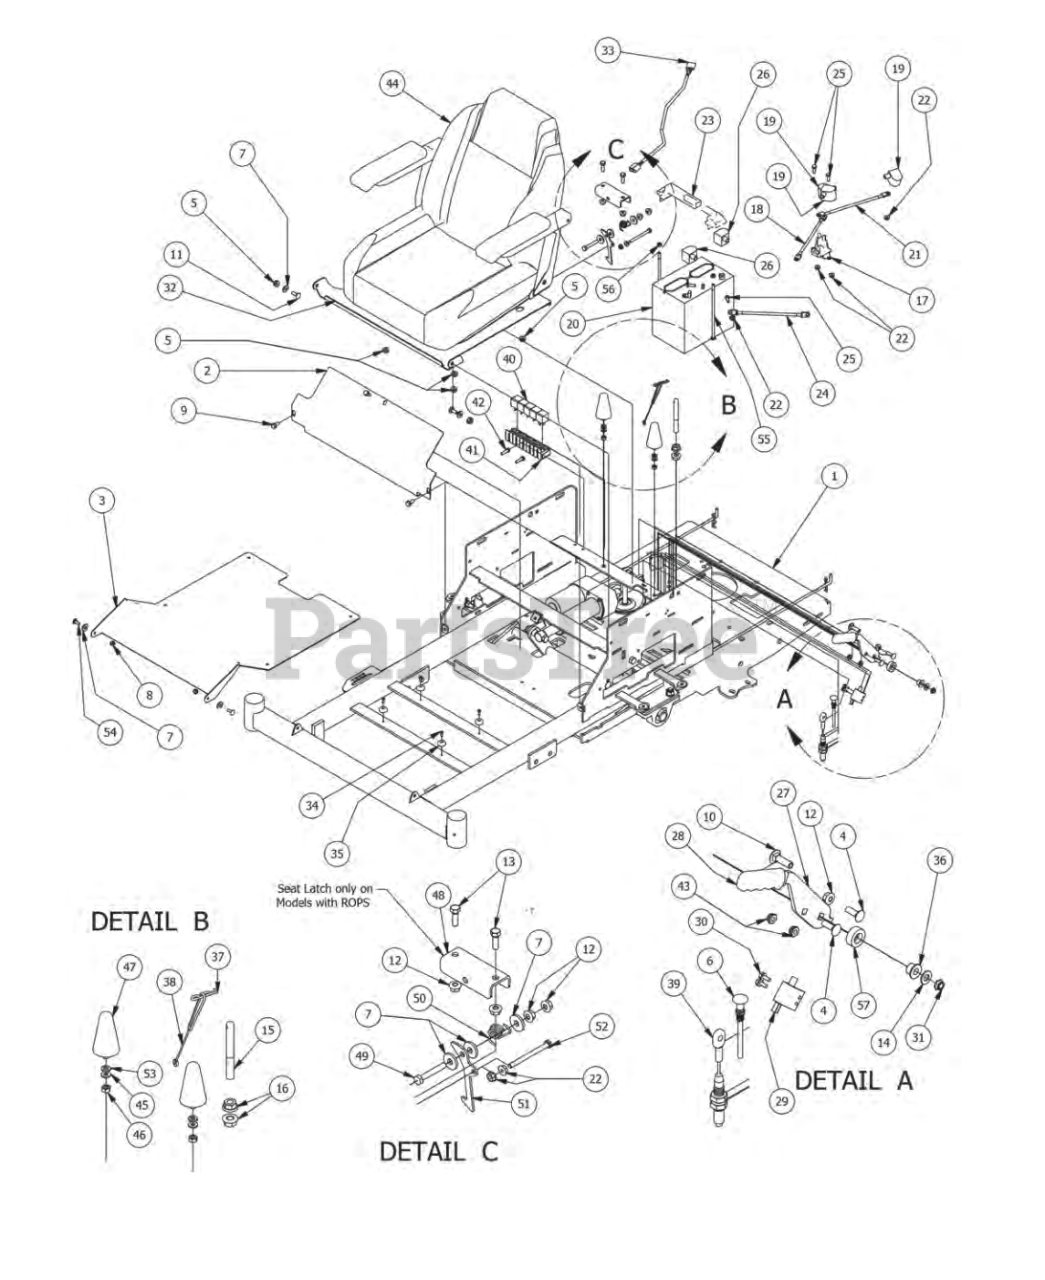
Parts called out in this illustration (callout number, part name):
1	ZT/CZT Frame 2013 Models
2	2013 ZT/CZT Cooler Cover
3	ZT/CZT FLOOR PANEL
4	5/16" x 1" Carriage Bolt
5	5/16-18 Nylon Flange Nut
7	.360 ID Plastic Washer
8	1/4" Nylock Nut
9	5/16 x 3/4 washer head type F screw
10	3/8" x 1 1/4" Carriage Bolt
11	5/16" x 7/8" Carriage Bolt
12	5/16" Flange Nut
13	5/16" x 1" Bolt
14	3/8" Flat Washer
15	Seat Braket Pin
16	1/2" Flange Nut
18	24 in red battery cable
21	12 in red battery cable
22	1/4-20 Hex Flange Nuts Zinc w/Serrations
23	Battery Hold Down
24	Starter to chassis cable
25	1/4-20 x 3/4 GR 5 Hex Bolts Zinc
26	Black Boot For ground cable
27	Brake Handle Cam Over
28	Rubber Brake Grip-cZT/ZT 2013
29	Safety Switch
30	12-24x 1/2 HWH Bolt
31	3/8 Nylock Jam Nut 1/2 Nut
32	2013 ZT Seat Plate
33	Seat Switch Adapter
34	# 10 x 1/2" Self Taping Screw
35	Button Bumper
36	Bronze Bushing SF-1220-8
37	Seat latch pin
38	seat pin lanyard
39	Brake Cable
40	Relay Terminal
41	Harness-ZT Only 2008 and up
42	1/4 x 1 Hex Head tek screw
43	5/16-18 Nylock Jam Nut 1/2 Nut
44	2013 ZT Seat
45	1/4" Flat Washer
47	Rubber Cone-1621-153
48	ZT/CZT Seat Latch Bracket
49	5/16-18 X 2 Hex C/S (GR.5) ZC
50	Torsion Spring for Seat latch
51	Seat Latch Lever
52	1/4 x 3 Hex Bolt - Grade 8 - ACS
53	5/16" Lock Washer
54	1/4" x 3/4" Carriage Bolt
55	1/4-20 X 8 Carriage Bolt
56	1/4-20 Hex Nut
57	2015 Brake Lever Spacer
